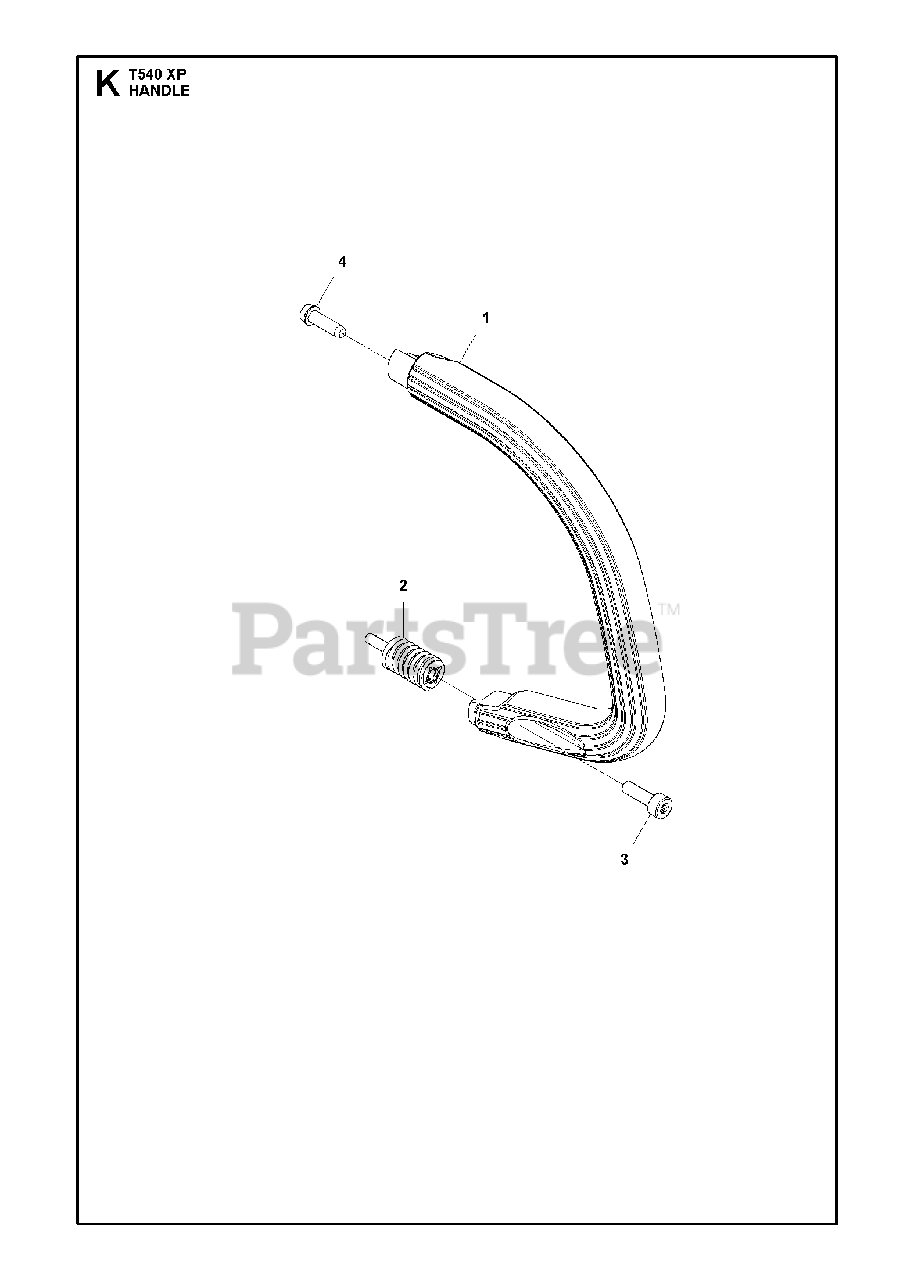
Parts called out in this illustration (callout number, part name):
1	FRONT HANDLE
2	ANTIVIBRATION ELEMENT
3	SCREW ITXSCM M6X20 T27 10.9 Z
4	SCREW ITXSCFT
